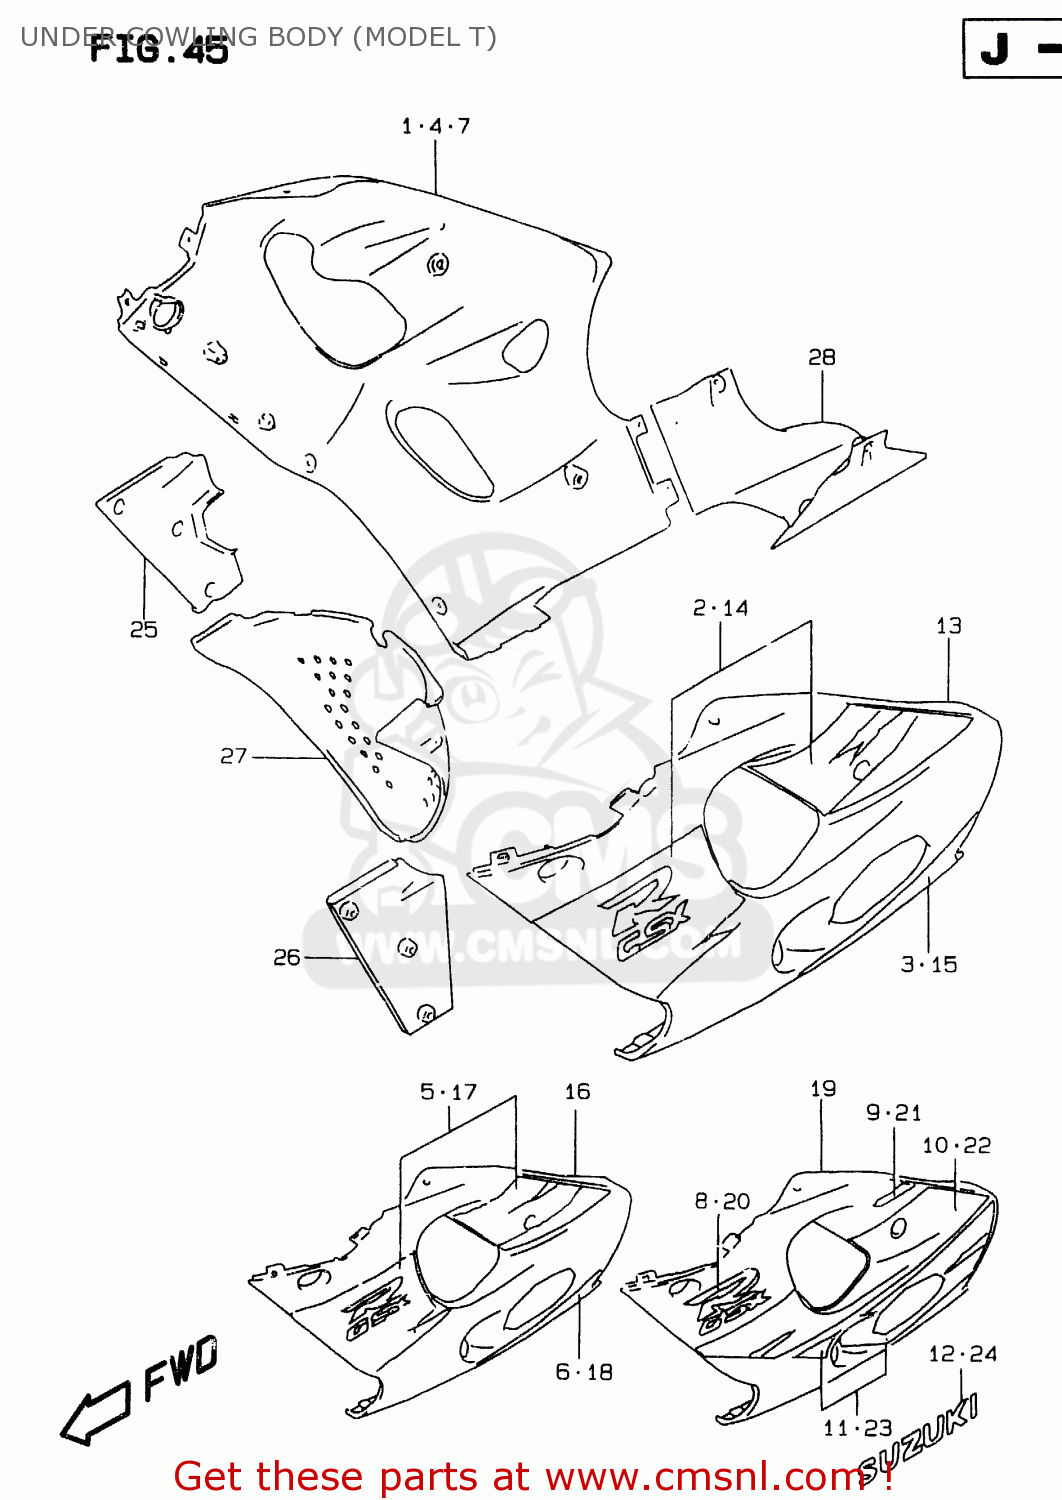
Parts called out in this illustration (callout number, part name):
1	COWLING, UNDER RH (PURPLE)
2	TAPE SET,COWL UNDER,R (YELLOW)
3	TAPE, LOWER RH (GRAY)
4	COWLING ASSEMBLY,UNDER,RIGHT (
5	TAPE SET,COWL UNDER,R
6	TAPE,COWL UNDER,R
7	COWLING ASSEMBLY,UNDER,RIGHT
8	EMBLEM,COWLING UNDER
9	TAPE,COWL UNDER UPR,R
10	TAPE,COWL UNDER CTR,R
11	TAPE SET,COWL UNDER LWR,R
12	EMBLEM,SUZUKI(BLUE)
13	COWLING, UNDER LH (PURPLE)
14	TAPE,COWL UNDER,L
15	TAPE,COWL UNDER,L
16	COWLING ASSEMBLY,UNDER,LEFT (
17	TAPE SET,COWLING,UNDER
18	TAPE,COWL UNDER,L
19	COWLING ASSEMBLY,UNDER,LEFT
20	EMBLEM,COWLING UNDER
21	TAPE,COWL UNDER UPR,L
22	TAPE,COWL UNDER CTR,L
23	TAPE SET,COWL UNDER LWR,L
24	EMBLEM,SUZUKI(BLUE)
25	COWLING,UNDER INNER,R
26	COWLING,UNDER,INNER,LEFT
27	COWLING,UNDER,CENTER
28	COWLING ASSY,UNDER RR
